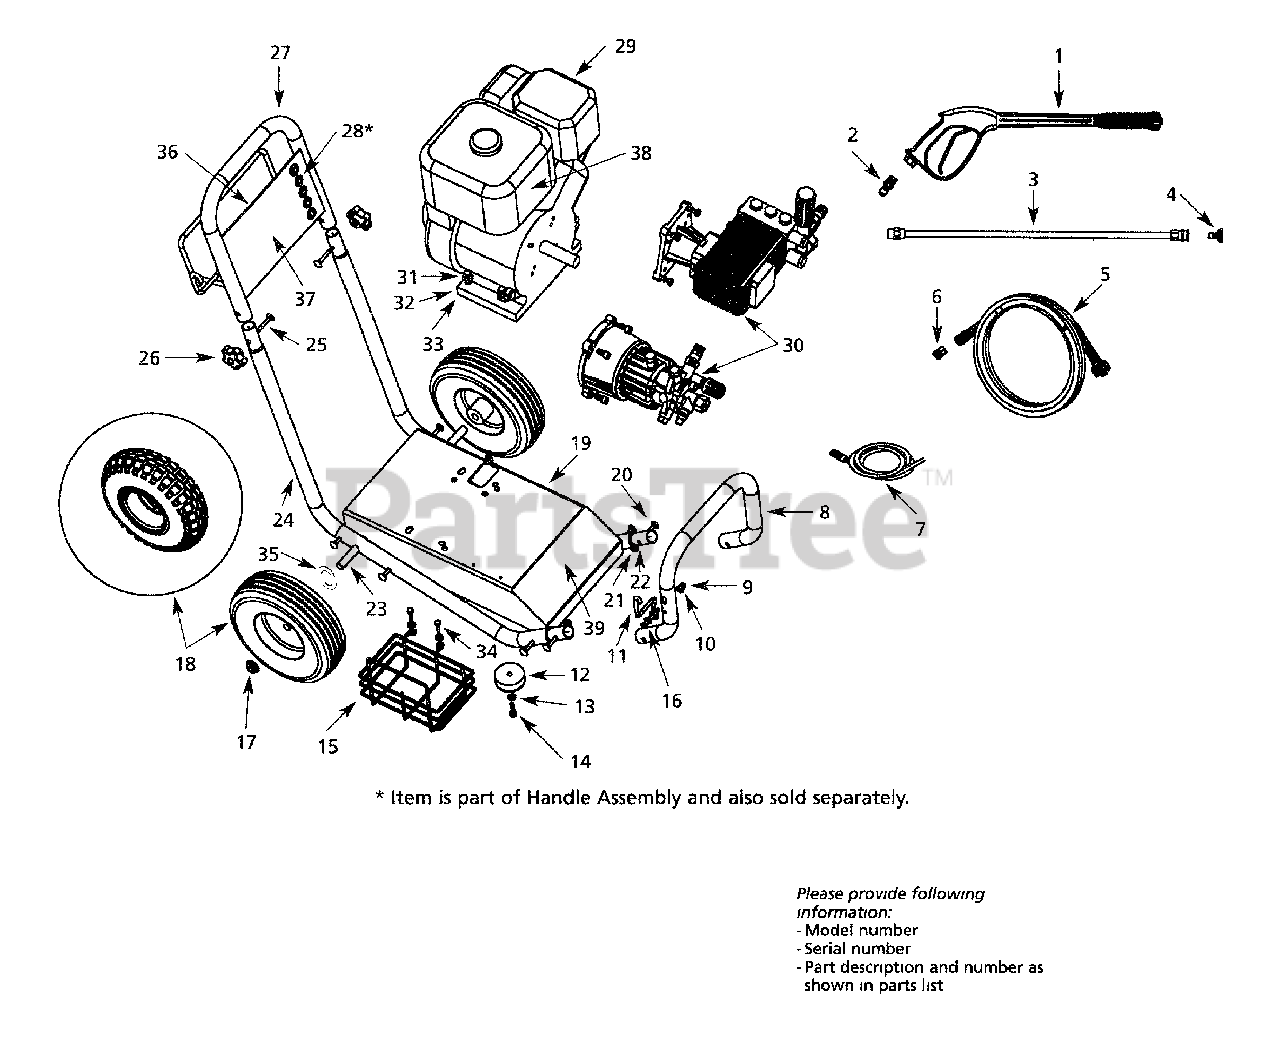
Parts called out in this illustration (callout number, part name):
2	Gun quick connect fitting
3	Lance
4	Spray tip - 0 degree
6	Hose quick connect fitting
7	Chemical filter and hose
8	Pump Guard
9	1/4-20 elastic stop nut
10	1/4" flat washer
11	Lance support
12	Rubber Bumper
13	1/4" "Wide" flat washer
14	1/4-20 x 1-1/4 self-tapping screw
15	Chemical Basket
16	1/4-20 x 2" bolt
17	Palnut
18	Wheel, Knobby tread
19	Baseplate assembly
20	5/16-18 x 1-3/4" carriage bolt
21	5/16 elastic stop nut
22	Washer, 5/16 flat washer
25	5/16-18 x 2-1/4" carriage bolt
26	Star knobs
27	Handle assembly
28	Rubber grommet
30	Pump assembly
31	3/8-16 x 1-3/4 hex head bolt
32	3/8" Flat washer
33	3/8-16 elastic stop nut
34	1/4-20 X 1" bolt
35	Axle bushing (thick washer)
36	Caution/warning decal
37	Placard/performance decal
38	Tory-Bilt logo decal
39	Troy-Bilt logo decal
